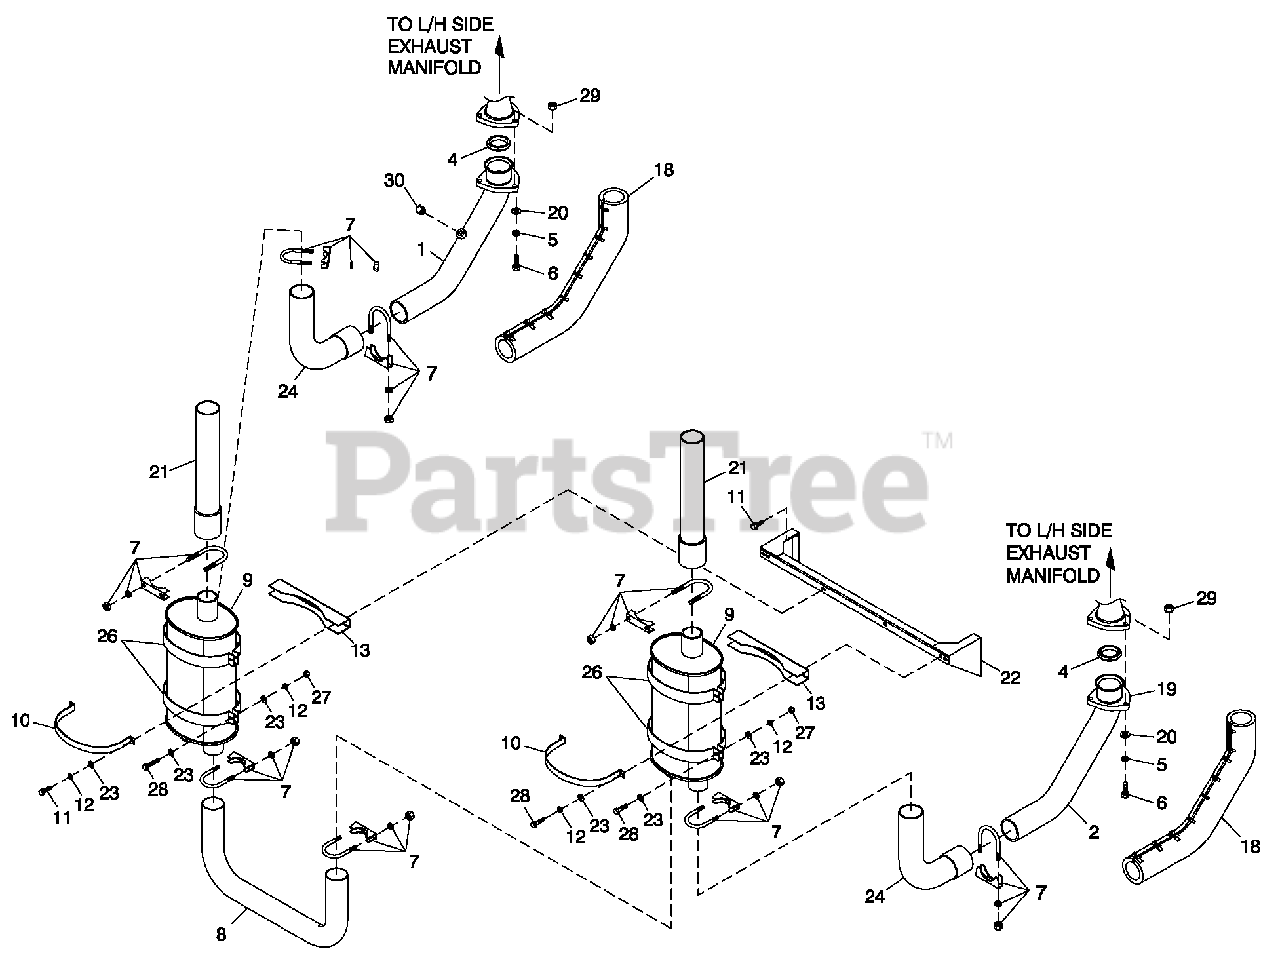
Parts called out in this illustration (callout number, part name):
1	PIPE EXH MAN R/H 6.8L G/B CPL (6.8L C5)
2	PIPE EXH MAN L/H 6.8L G/B CPL (6.8L C5)
4	RING GASKET 2.5 DIA
5	WASHER LOCK M10 SS
6	SCREW HHC M10-1.5 X 50 SS FTH
7	BOLT U 3/8-16 X 2.62
8	PIPE EXHAUST CROSSOVER
9	MFLR 7" X 9" X 25" (2) 2.5" IN/2.5" OUT
10	MUFFLER STRAP
11	SCREW THF M6-1 X 16 N WA Z/JS
12	WASHER LOCK M6-1/4
13	MUFFLER BRACKET STIFFENER
18	EXHAUST BLANKET 900MM LONG (6.8L C5)
19	FLANGE EXHAUST
20	WASHER FLAT 3/8 SS
21	EXHUAST OUTLET PIPE CPL
22	BRKT MUFFLER
23	WASHER FLAT 1/4-M6 ZINC
24	PIPE ELBOW EXHAUST MUFFLER
26	MUFFLER STRAP UPPER/LOWER
27	NUT HEX M6 X 1.0 G8 YEL CHR
28	SCREW HHC M6-1.0 X 35 G8.8 BLK
29	NUT HEX M10-1.5 SS
30	PLUG M18-1.50
